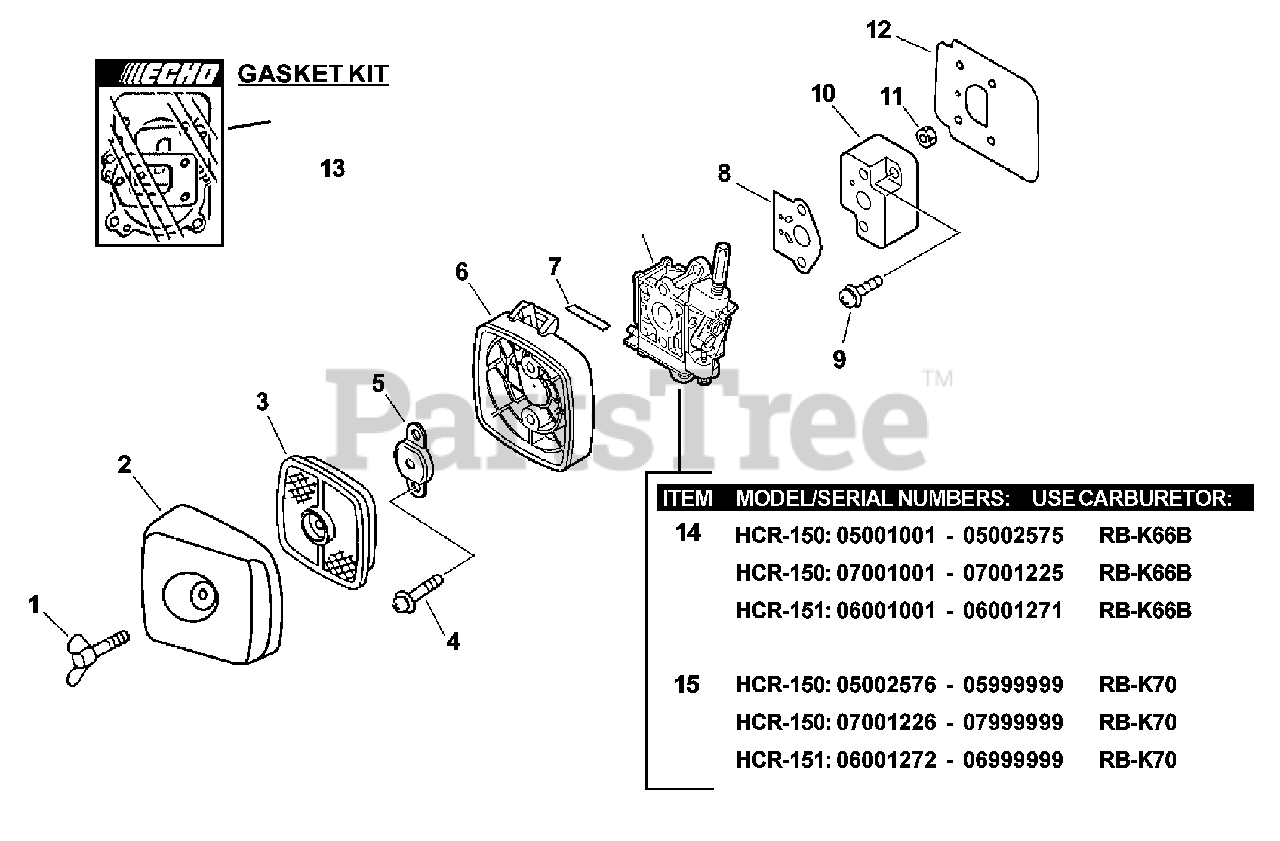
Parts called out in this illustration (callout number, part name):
1	THUMBSCREW
2	COVER, AIR FILTER - GRAY
3	FILTER, AIR - SINGLE LAYER
4	SCREW - 5X65
5	PLATE, PREVENT
6	CASE, AIR FILTER - GRAY
7	LABEL - CHOKE
8	GASKET, INTAKE
9	SCREW - 5X20
10	INSULATOR, INTAKE
12	SHIELD, INTAKE
13	GASKET KIT
14	CARBURETOR RB-K66B
15	CARBURETOR RB-K70
